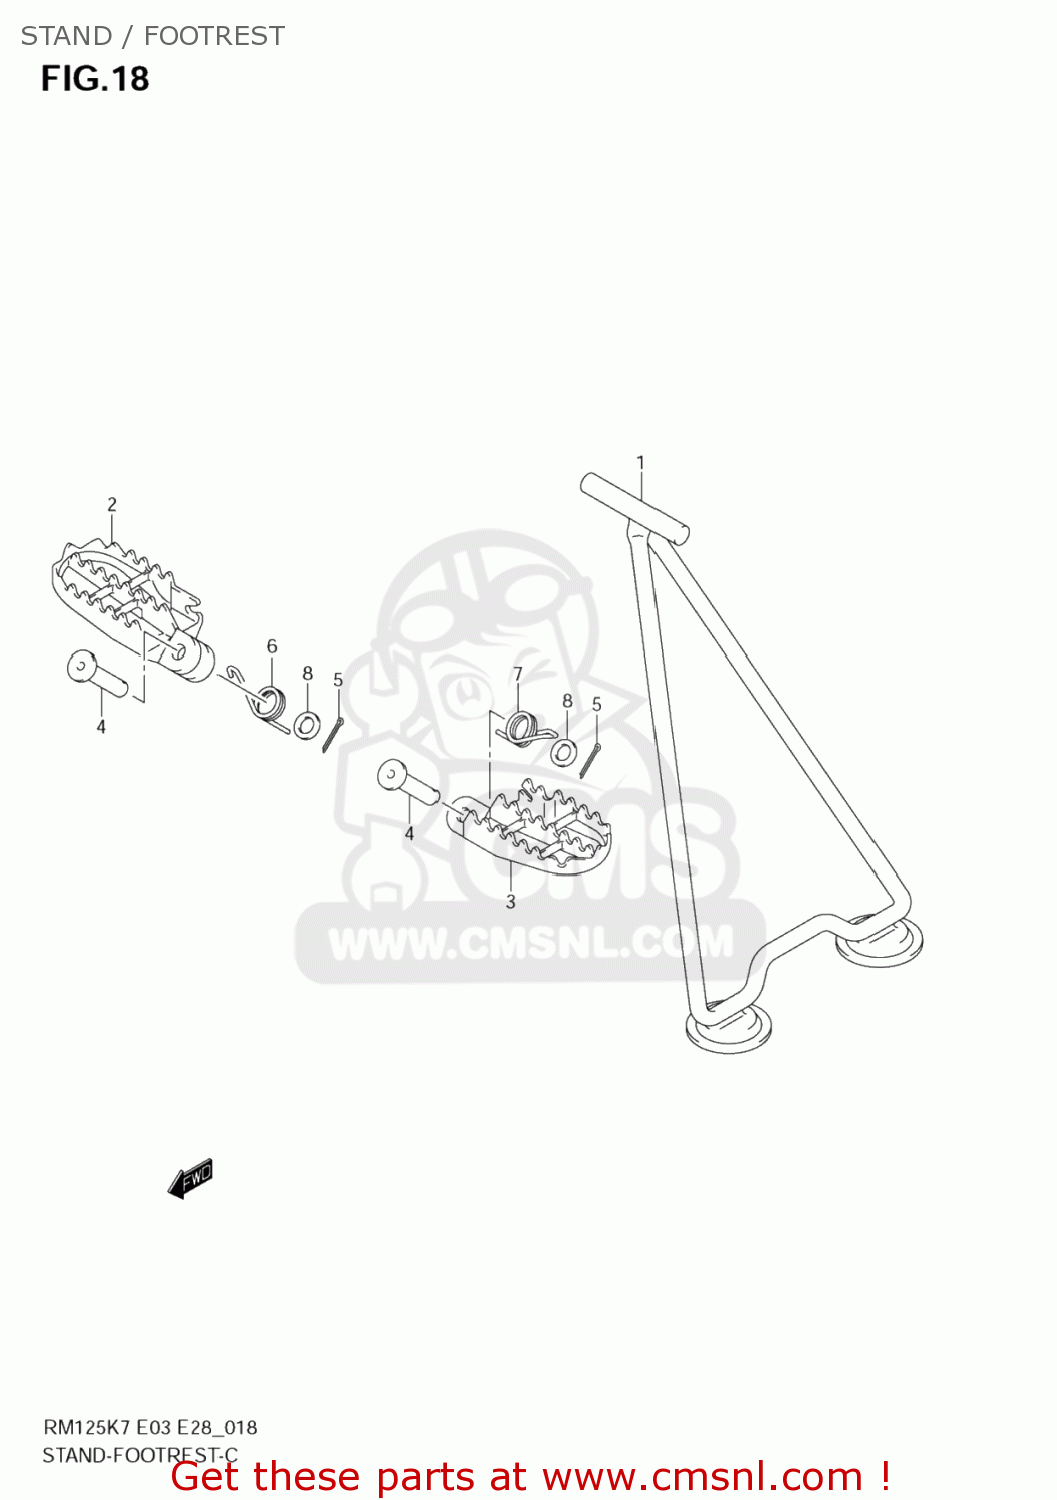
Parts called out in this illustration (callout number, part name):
1	STAND
2	FOOTREST,R(BLACK)
3	FOOTREST,L
4	PIN
5	PIN
6	SPRING
7	SPRING
8	WASHER
